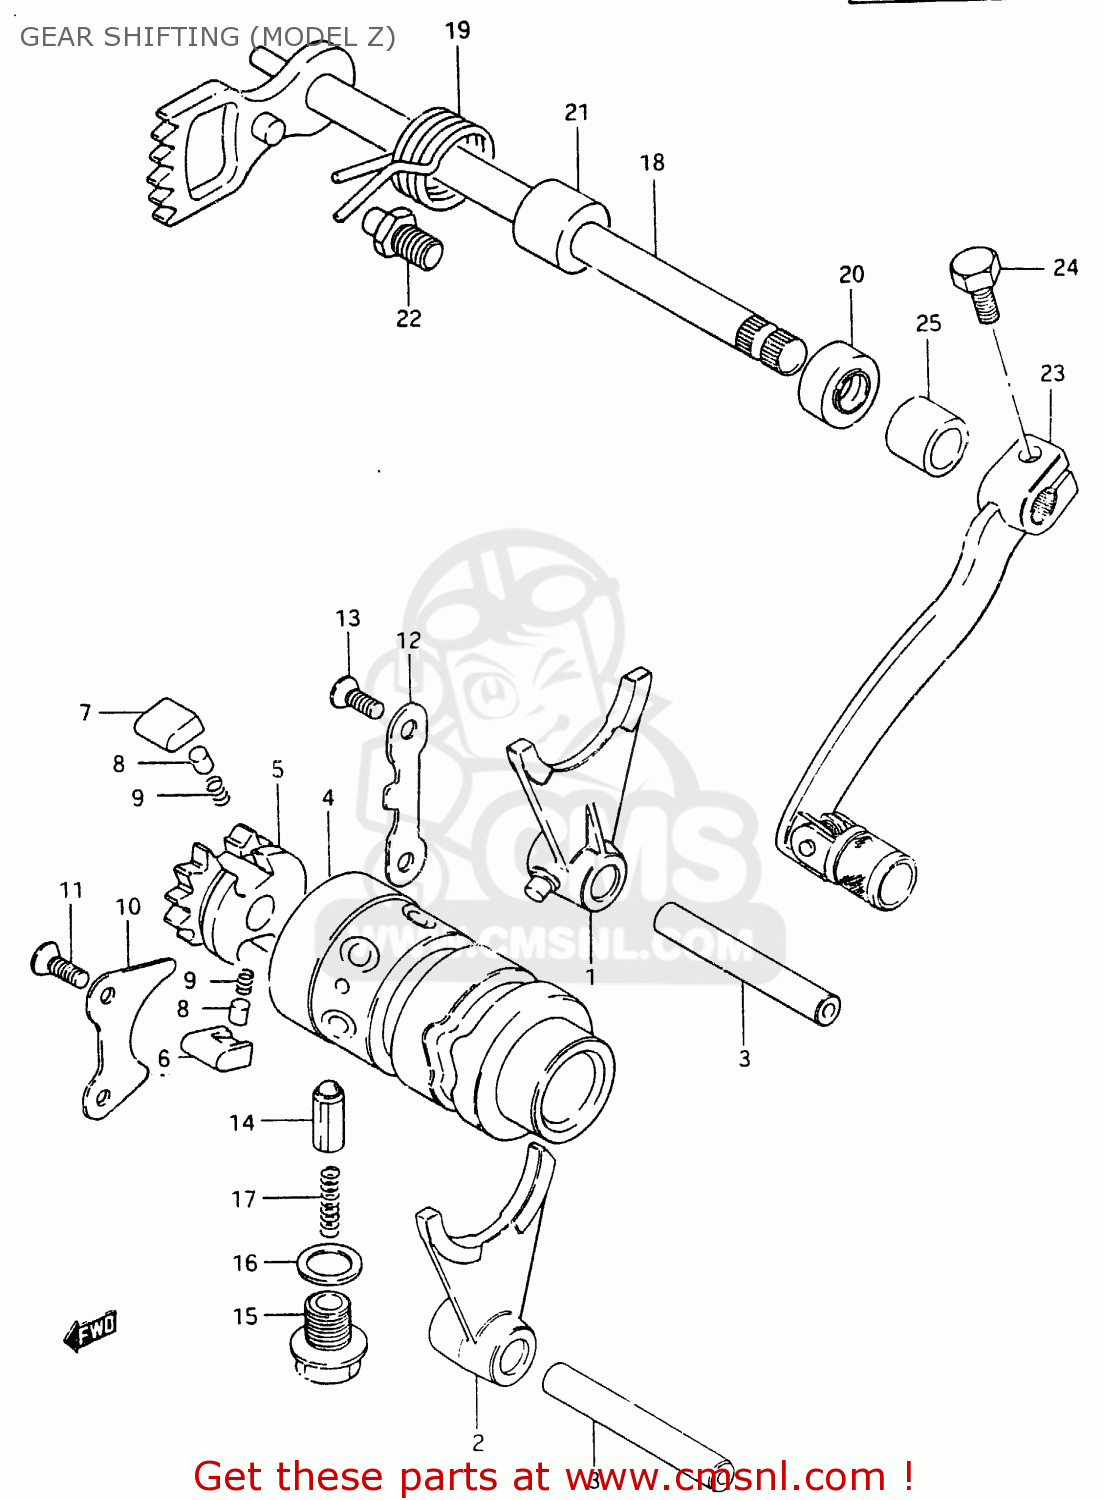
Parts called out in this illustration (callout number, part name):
1	FORK,GEAR SHIFT NO.1
2	FORK,GEAR SHIFT NO.2
3	SHAFT,GEAR SHIFT FORK
4	CAM,GEAR SHIFT
5	RETAINER,GEAR SHIFT CAM
6	PAWL,GEAR SHIFT NO.1
7	PAWL,GEAR SHIFT NO.2
8	PIN(5X8)
9	SPRING
10	LIFTER,GEAR SHIFT PAWL
11	SCREW
12	GUIDE,GEAR SHIFT CAM
13	SCREW
14	STOPPER,GEAR SHIFTING
15	BOLT,GEAR SHAFT CAM STOPPER
16	GASKET(14X19.2X2) (NAS)
17	SPRING
18	SHAFT,GEAR SHIFT
19	SPRING
20	OIL SEAL
21	SPACER(12X20X15.3)
22	STOPPER,GEAR SHIFT CAM
23	LEVER ASSEMBLY,GEAR SHIFTING
24	BOLT
25	SPACER(12X20X15.3)
